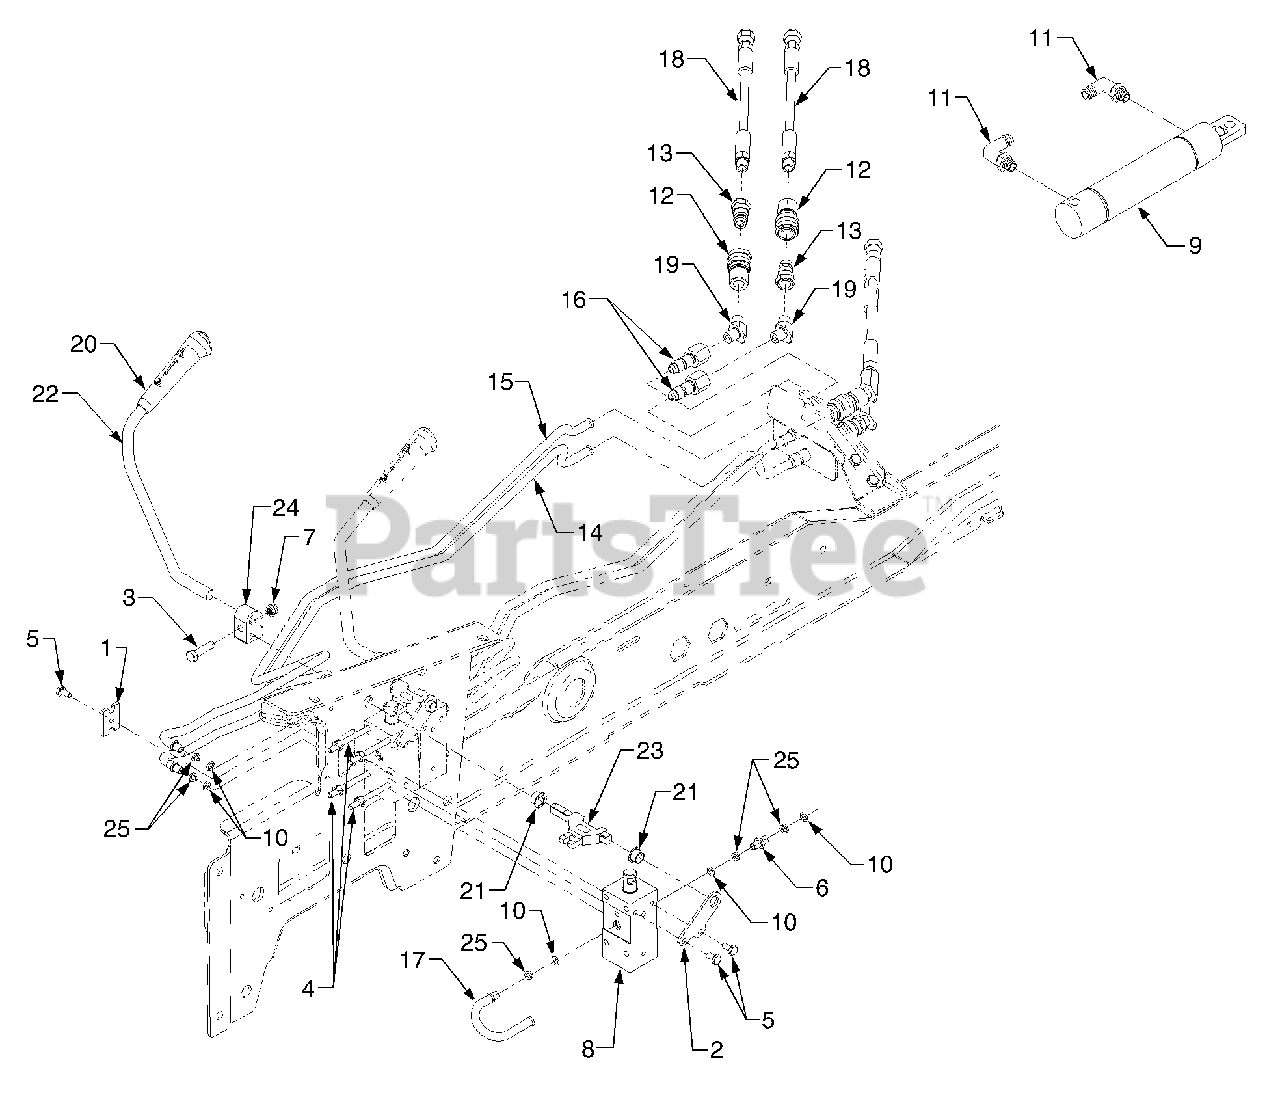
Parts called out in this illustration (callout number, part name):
1	Clamp, Double Valve
3	Screw, Hex Cap 5/16-18 x 1.25 GR5
4	Screw, Hex Cap 1/4-20 x 6.0 GR5
5	Screw, Hex Cap 1/4-20 x .5 GR5
6	Fitting, Union
7	Nut, Hex Insert Lock, 5/16-18
8	Valve Assembly, Hydraulic
9	Cylinder, Hitch Angling
10	O-Ring, .301 ID x .070 Dia
11	Elbow, 90 Degree
12	Fitting, Body Coupling
13	Fitting, Nose Coupling
14	Tube, Hydraulic Angle (Left)
15	Tube, Hydraulic Angle (Right)
16	Fitting, Bulkhead, 3/8 Tube
17	Tube, Hyd. Return, Aux. Valve #2
18	Hose, Angle
19	Fitting, Street Elbow, 45 Degree
20	Knob, Valve Handle
21	Bearing, Nylon Flange, .5 ID
22	Handle, Hydraulic Valve, Aux #2
23	Link, Lift
24	Clamp, Handle
25	O-Ring, Backup .327 x .433 x .05
